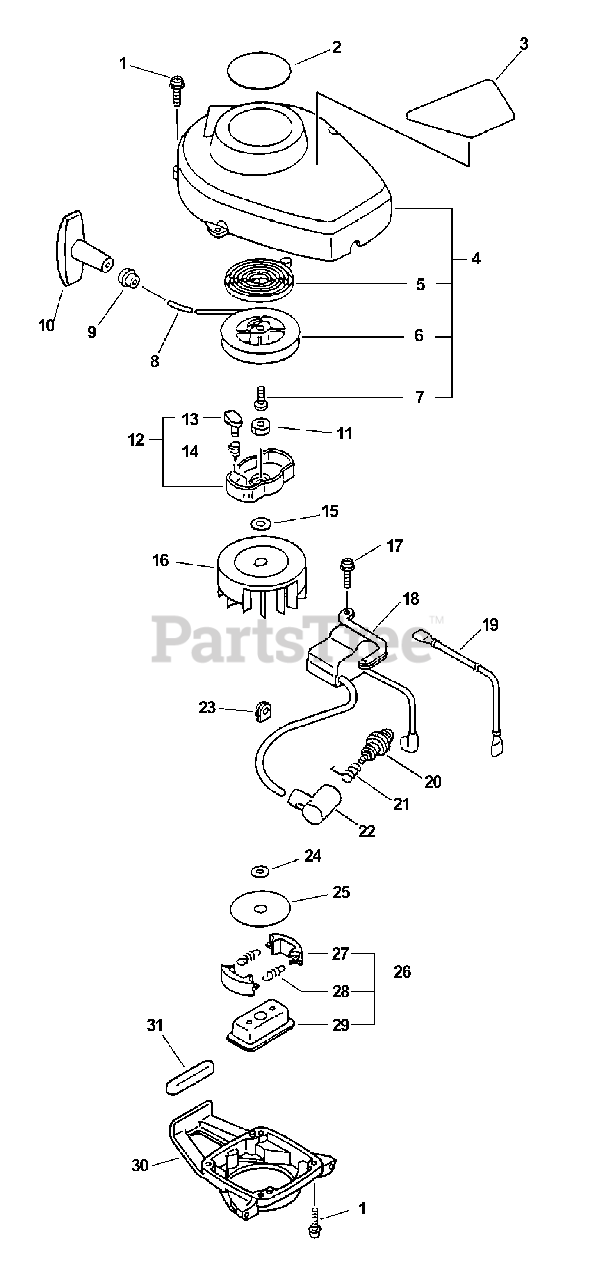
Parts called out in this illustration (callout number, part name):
1	SCREW - 4X16
2	LABEL - MODEL HC-2400
2	LABEL - MODEL HC-2410
3	LABEL - CAUTION
4	STARTER ASSY
5	SPRING, REWIND
6	REEL, ROPE
8	ROPE, STARTER - 3.5X1000
9	GUIDE, ROPE
10	GRIP, STARTER
11	NUT - LEFT HAND
12	STARTER PAWL ASSY
13	PAWL, STARTER - BLACK
14	SPRING, RETURN
15	WASHER - 8
16	FLYWHEEL
17	SCREW - 4X22
18	COIL, IGNITION
19	LEAD - IGNITION
20	SPARK PLUG -- BPM-7Y
21	TERMINAL, SPARK PLUG CAP
22	CAP, SPARK PLUG
24	WASHER, CLUTCH
25	PLATE, CLUTCH
26	CLUTCH ASSY
27	SHOE, CLUTCH
28	SPRING, CLUTCH
29	HUB, CLUTCH
30	CASE, CLUTCH
31	CUSHION, FUEL TANK
